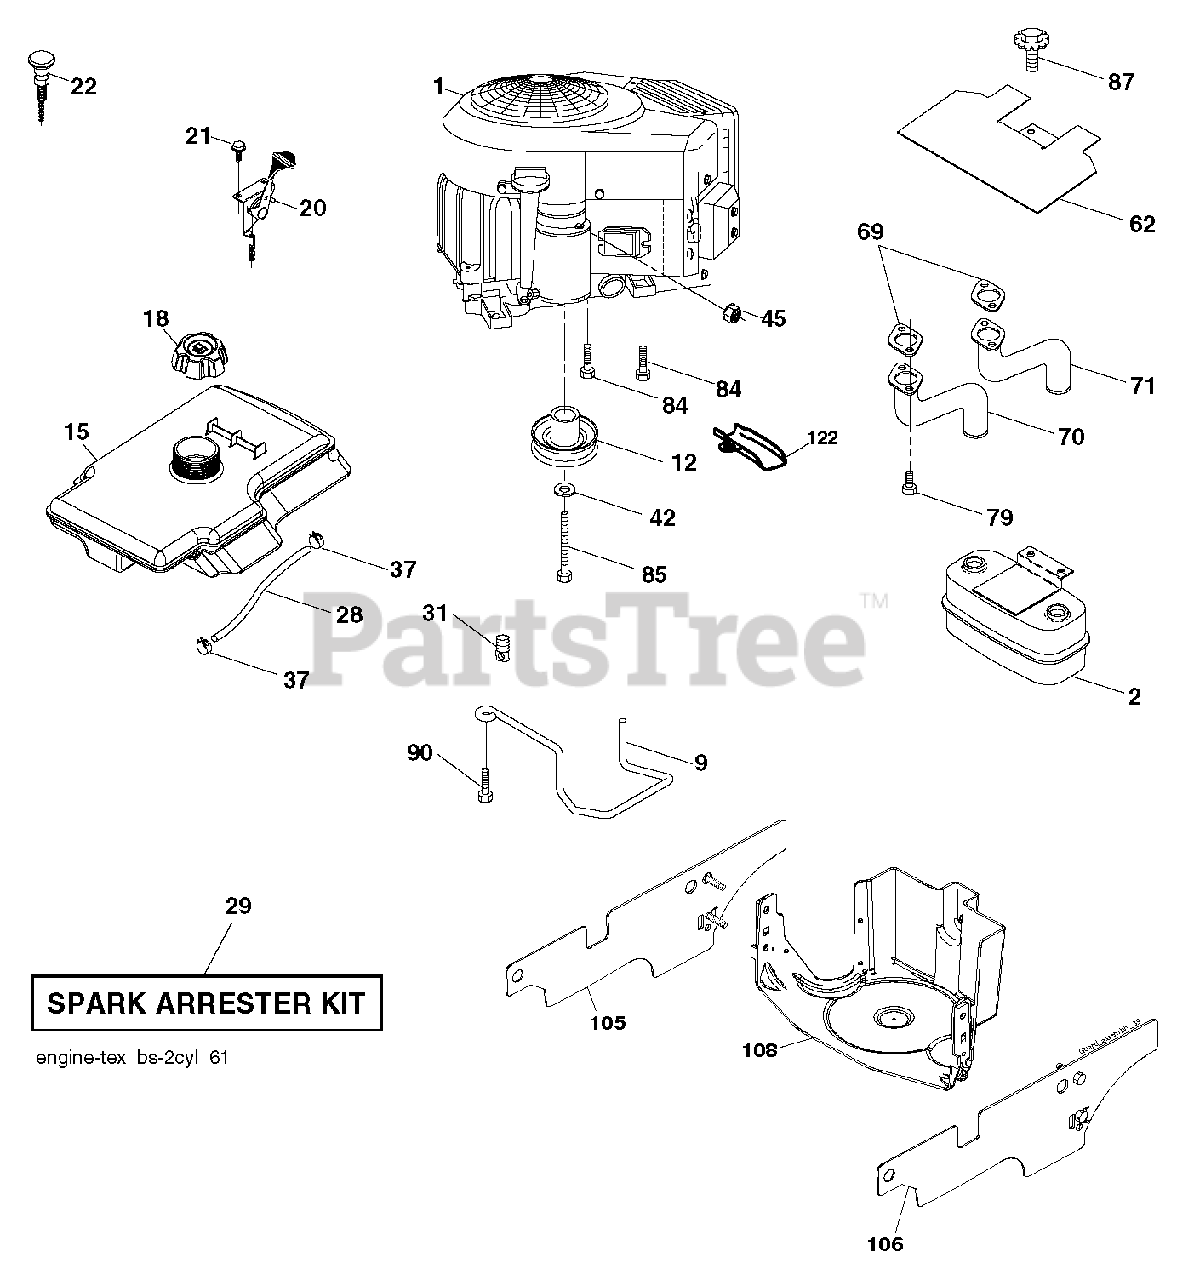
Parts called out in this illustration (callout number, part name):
2	MUFFLER.TWIN.CYL.LOW.TONE
9	KEEPER.BELT.ENGINE.4.2
12	PULLY ENGINE
18	CAP.ASM.FUEL.TANK.3"BLACK
20	THROTTLE CABLE
21	SCREW.#10 X 0.750.BOS THREAD
22	CONTROL CHOKE
29	ARRESTER SPARK (OPTIONAL)
31	BUSHING.1.375OD
37	HOSE CLAMP
42	LOCKWASHER
45	NUT
62	RP SHIELD HEAT MUFFLER
69	GASKET.MUFFLER
70	TUBE MANIFOLD LH
71	EXHAUST TUBE RH
79	SCREW.SOCKET.HEAD.5/16-18
84	SCREW.3/8-16
85	BOLT HEX 7/16-20X4-1/4"
87	BOLT, 5/16-18 X 1 3/4
90	SCREW 3/8-16X1
122	EXTENSION DRAIN OIL
